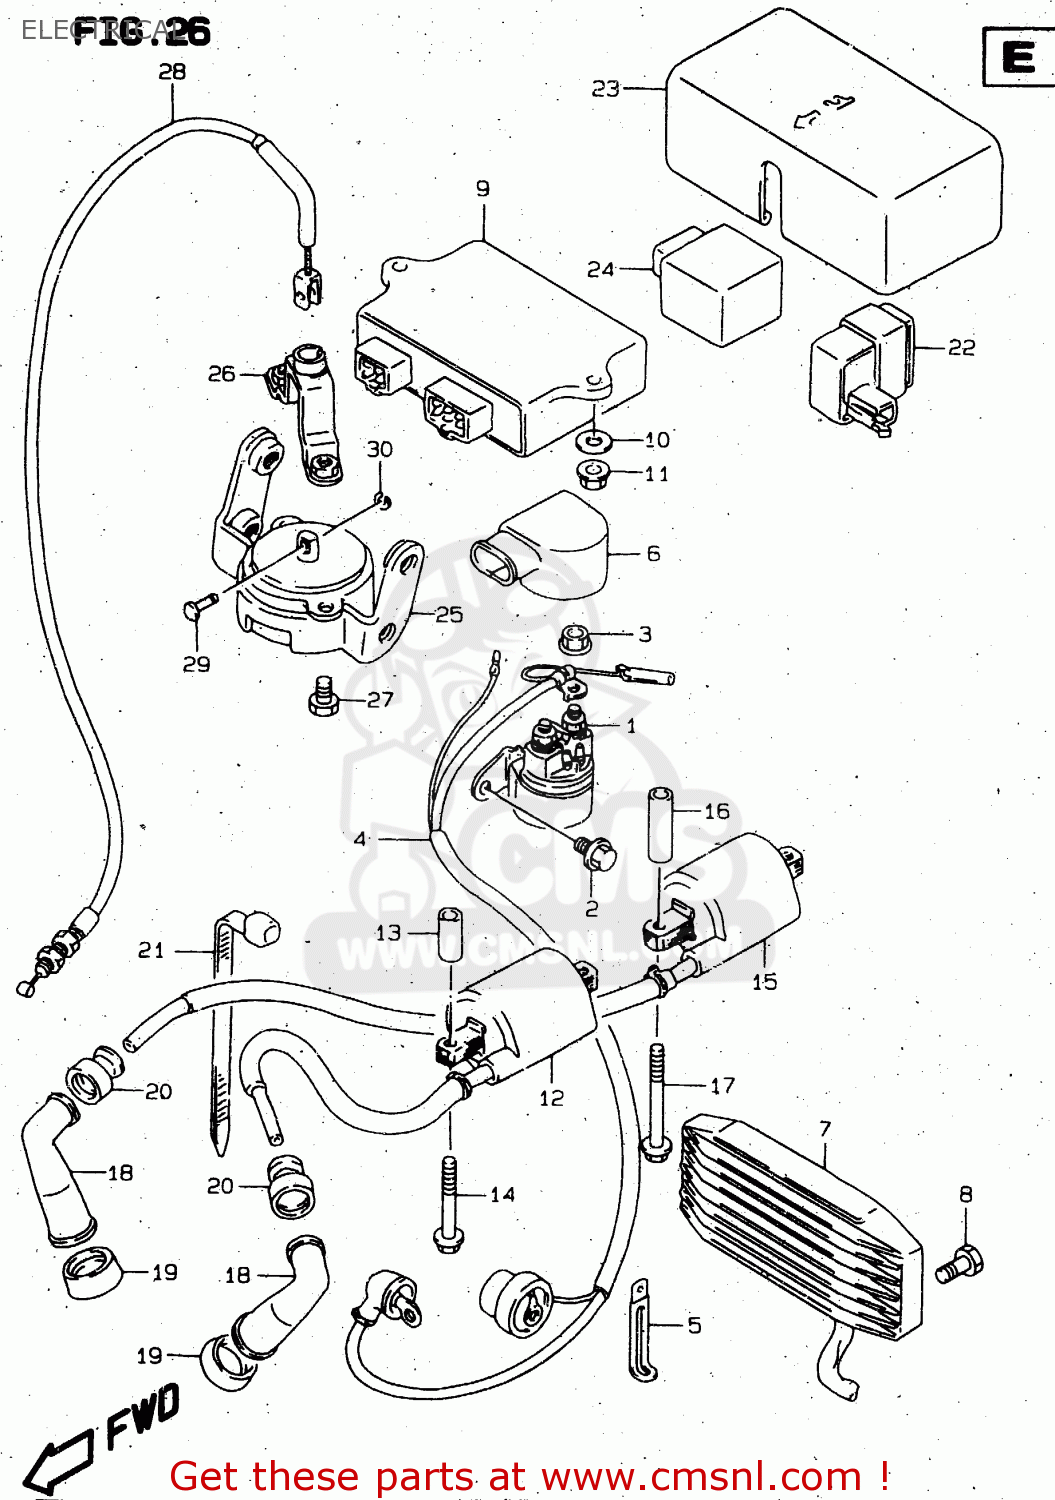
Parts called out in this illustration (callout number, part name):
1	RELAY ASSY,STARTING MOTOR
2	BOLT
3	NUT
4	WIRE,STARTER MOTOR LEAD
5	CLAMP(L:65)
6	CAP,STARTER RELAY TERMINAL
7	RECTIFIER ASSY
8	BOLT
9	IGNITOR ASSY
10	WASHER
11	NUT
12	COIL ASSY,IGNITION RR
13	SPACER(6.4X10X22)
14	BOLT
15	COIL ASSY,IGNITION
16	SPACER(6.4X10X32)
17	BOLT
18	CAP,SPARK PLUG
19	SEAL,SPARK PLUG CAP
20	SEAL,HIGH TENSION CORD
21	CLAMP(L:125)
22	RELAY ASSY,FUEL CUT
23	COVER,RELAY
24	CONTROL UNIT,DECOMP
25	SOLENOID ASSY,DECOMP
26	BRACKET,DECOMP SOLENOID
27	BOLT
28	CABLE ASSEMBLY,DECOMPRESSION
29	PIN(4X12.5)
30	E RING
